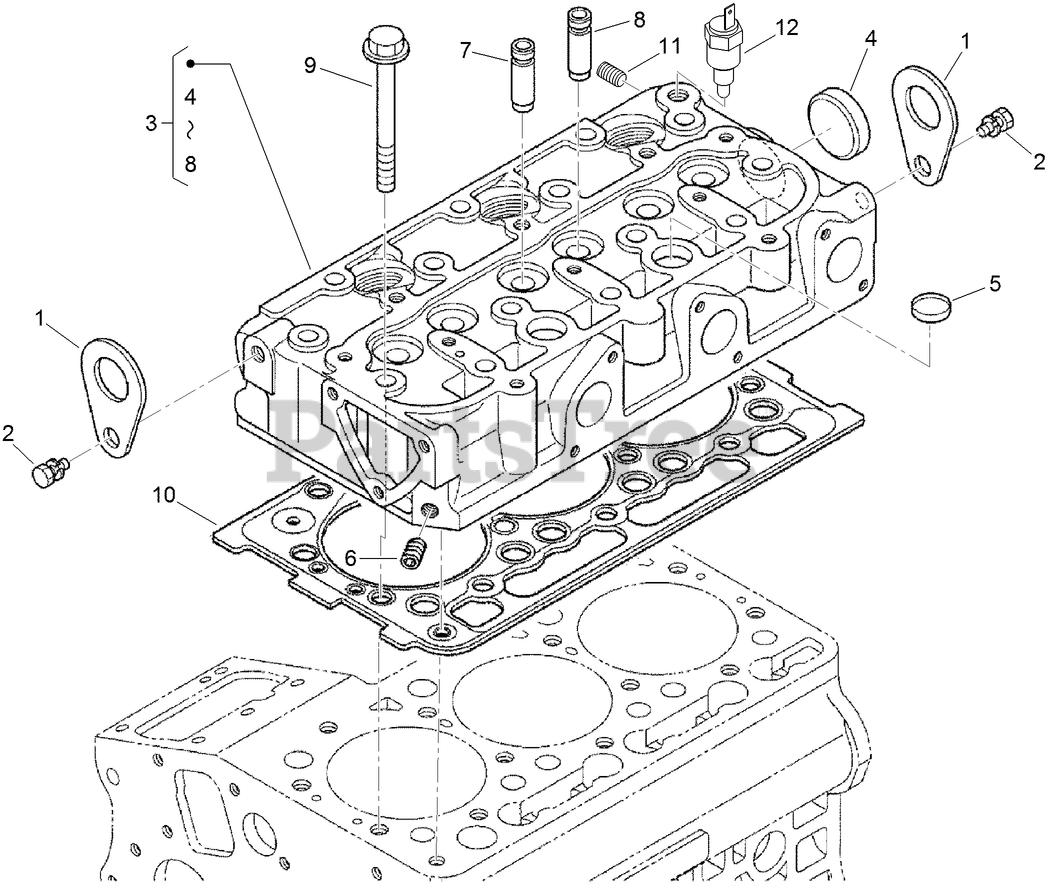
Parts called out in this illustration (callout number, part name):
1	HOOK-ENGINE
3	HEAD-CYLINDER
4	CAP-SEALING
5	CAP-SEALING
7	GUIDE-VALVE, INLET
8	GUIDE-VALVE, EXHAUST
9	BOLT-HEAD, CYLINDER
10	GASKET-HEAD, CYLINDER
12	THERMOSWITCH
